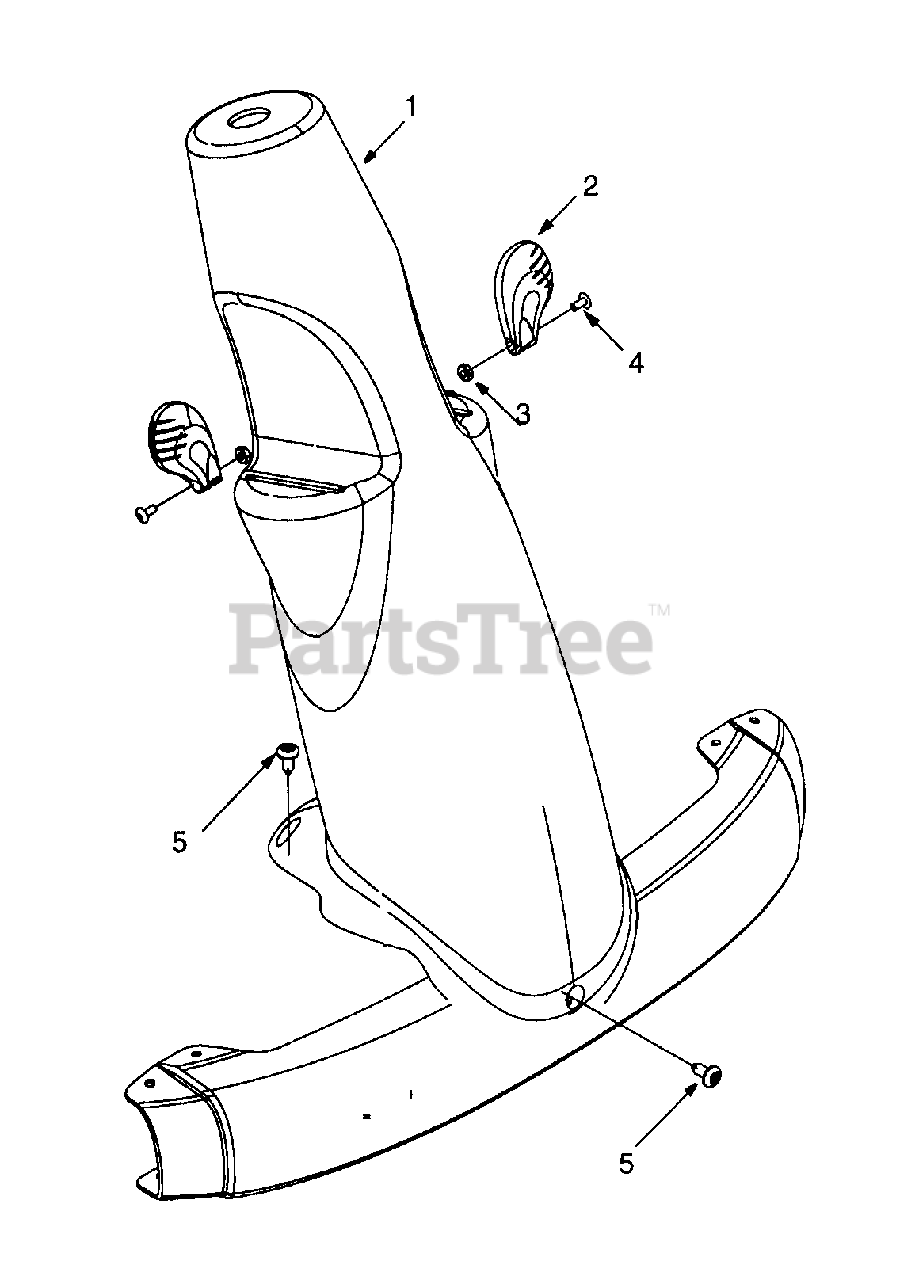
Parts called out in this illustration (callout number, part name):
1	Steering Column: Black
2	Control Knob
3	Hex Nut 8-32
4	Pan Head Machine Screw #8-32
5	Hex Screw TT 1/4-20 x .50"
